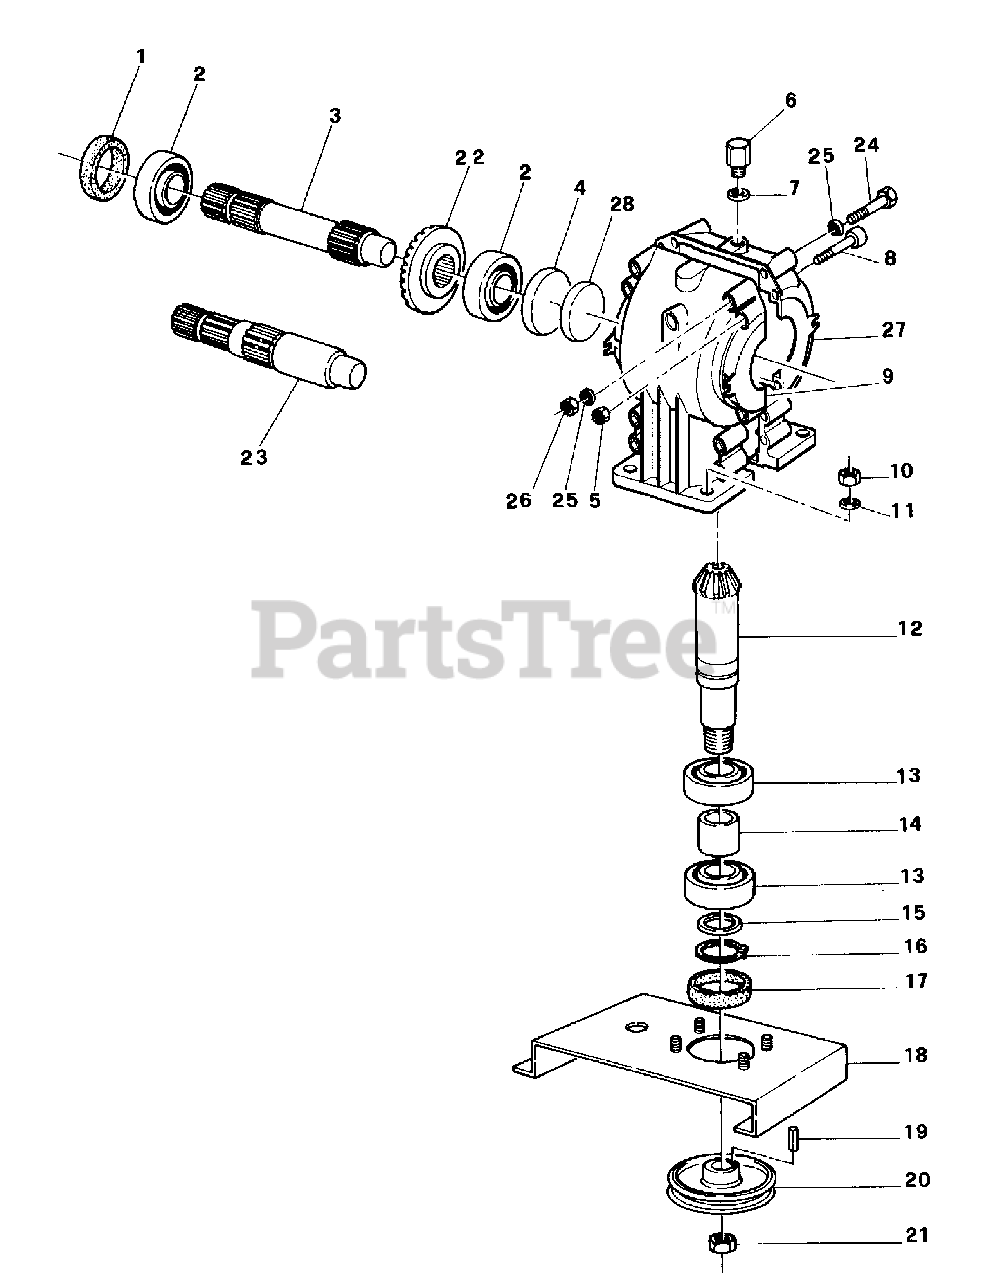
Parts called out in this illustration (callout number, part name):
1	Oil Seal 40.68.10
2	Bearing 6208
3	Input Shaft
4	Cover
5	Nut M8
6	Breather Cap
7	Gasket
8	Bolt TCEI 8 x 50
9	Gearbox Housing w/o Hole
10	Nut M12
11	Lock Washer M12
12	Pinion Gear
13	Bearing 6207
14	Spacer
15	Spacer Washer
16	Snap Ring Outer M36
17	Oil Seal 35.62.10
18	Central Plate 60''
19	Key 7 x 8 x 35
20	Pulley SPB 250 x 1
21	Nut M25
22	Ring Gear
23	Input Shaft w.CCW Rotation
24	Bolt 10 x 120
25	Flat Washer M10
26	Nut M10
